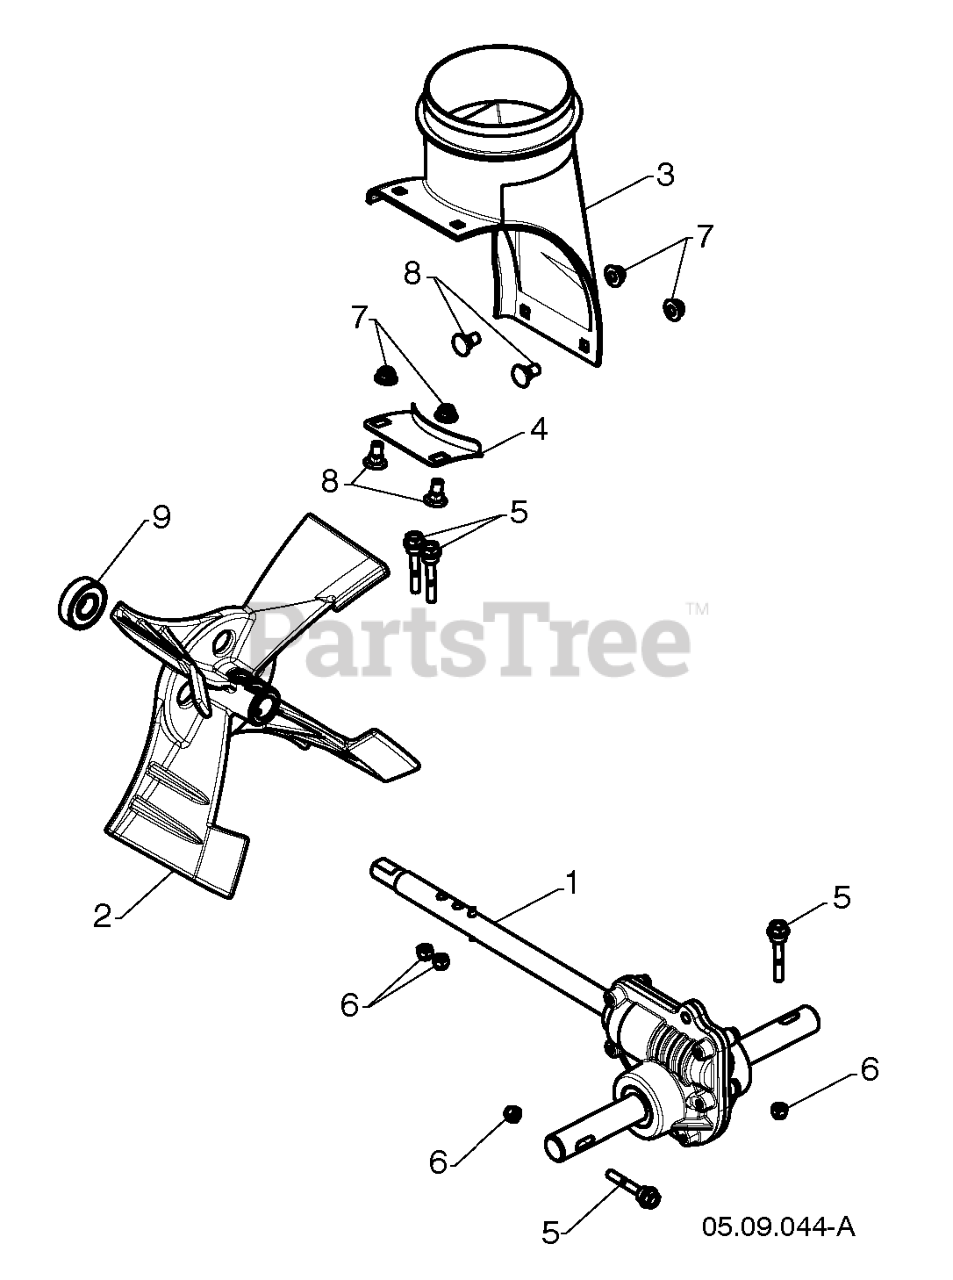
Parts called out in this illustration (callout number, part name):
1	LEVER/CABLE.ASM.ROTATOR
3	CHUTE.ROT.HEAD.SERVICE
4	SNOW.PIVOT.BRKT.BLK.SERVICE
5	SNOW.PIVOT.PULLY
6	SNOW.CBL.ASM.ADJ.SERVICE(74)
7	SNOW.CBL.ASM.SERVICE(428272)
